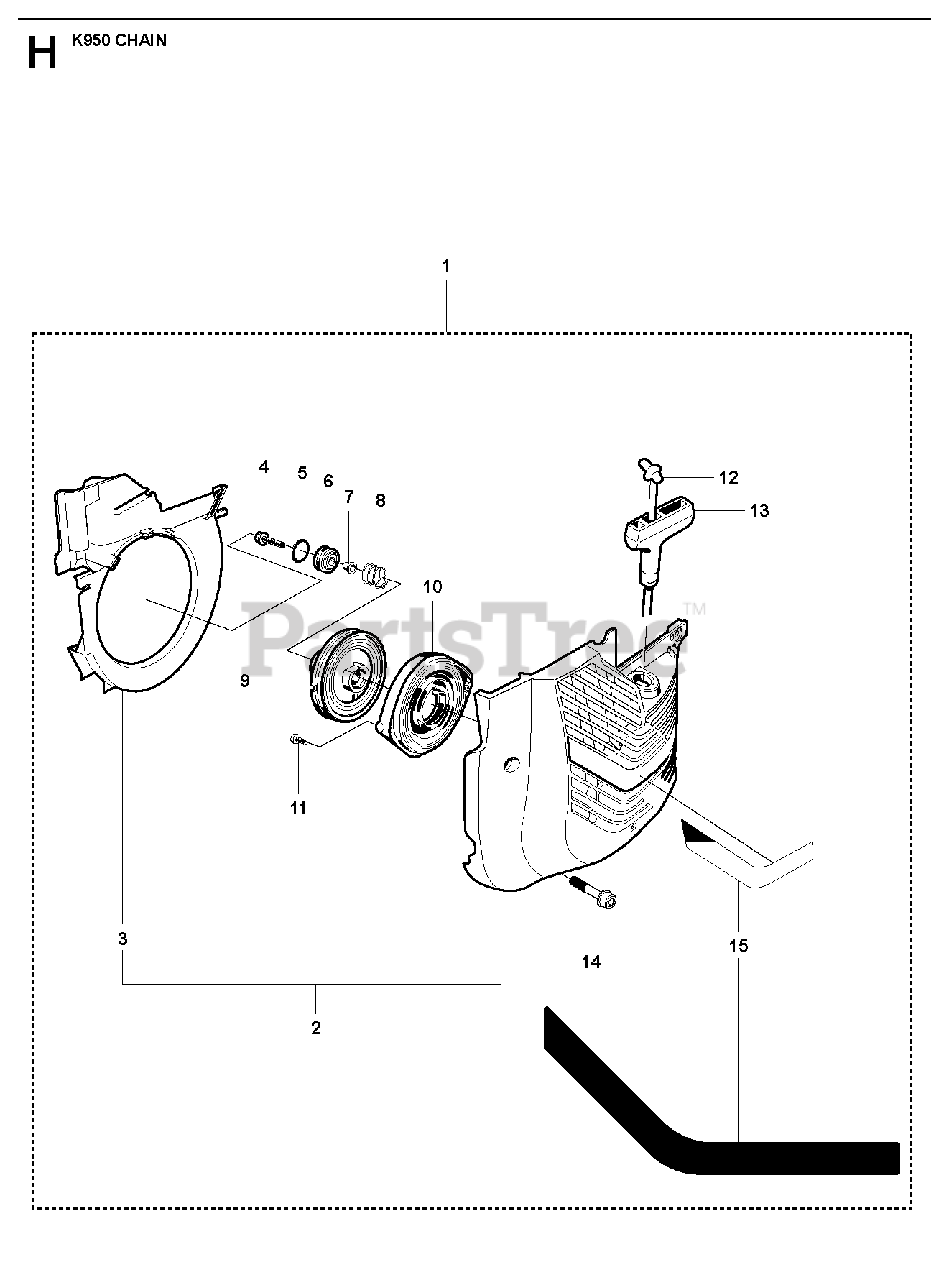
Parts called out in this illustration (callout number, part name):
4	SCREW IHSCFT
6	GROMMET
7	SPACING SLEEVE
8	COMPRESSION SPRING
9	STARTER PULLEY
10	RECOIL SPRING
10	SCREW CCRPANT
12	STARTER CORD50 m. coil
13	STARTER HANDLE
14	SCREW IHSCFMO
